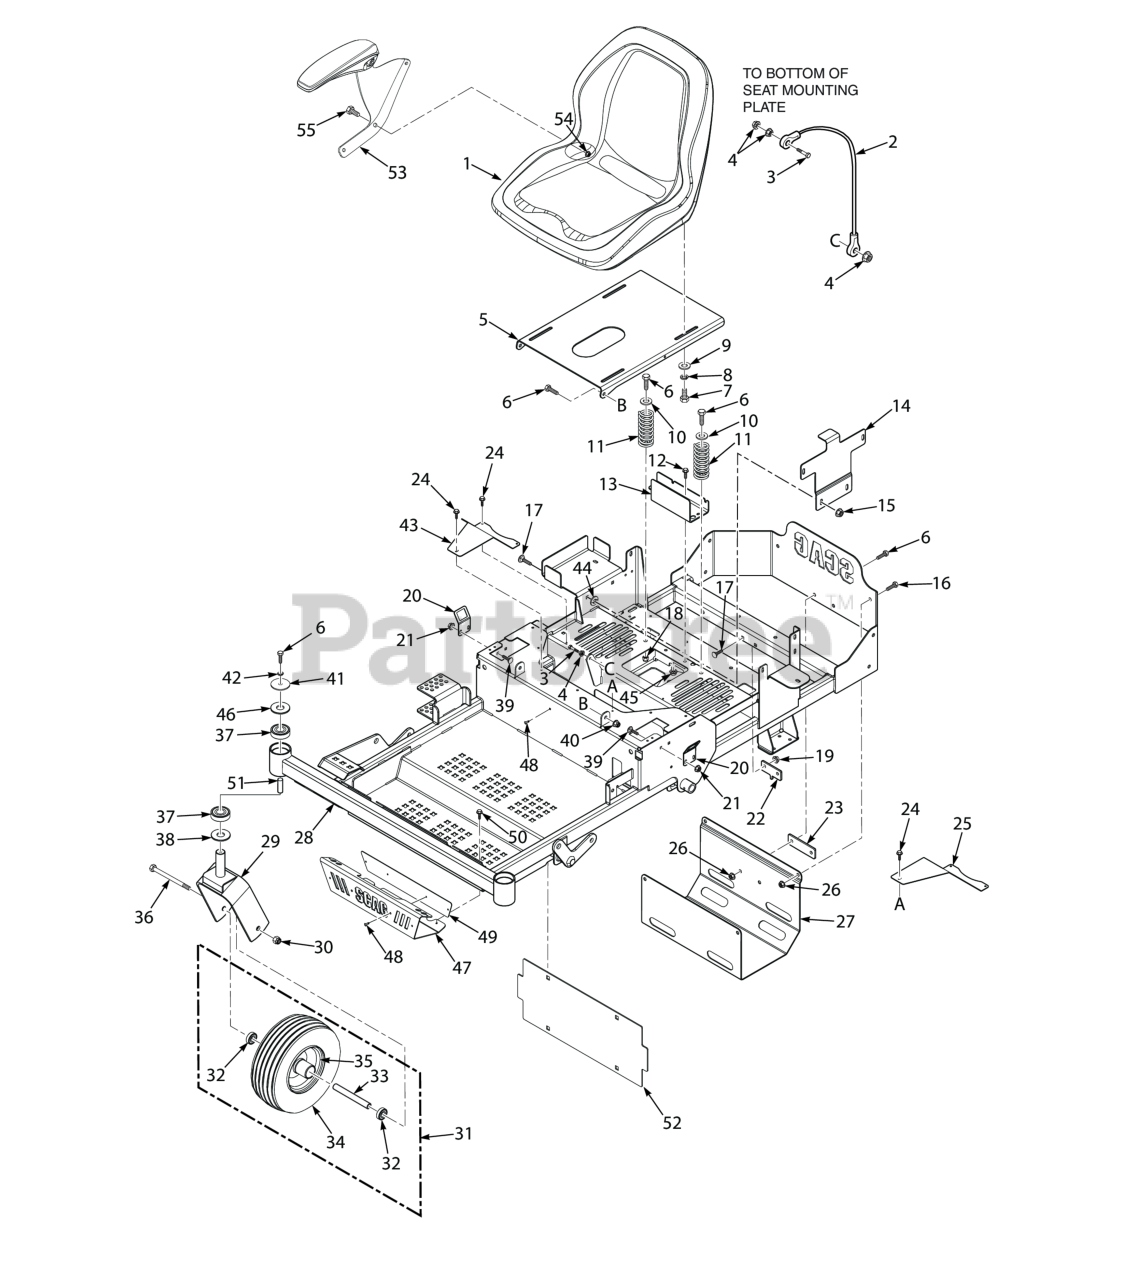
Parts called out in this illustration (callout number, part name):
1	Seat, SZL w/Armrests
2	Cable, Seat Stop
3	SERR. FLG. HEX HEAD CAPSCREW, 5/16-18 X 3/4
4	NUT, 1/4-20 SERRATED FLANGE HEX HEAD
5	Seat-Plate W/Decal
6	Bolt, Hex Head, 3/8-16 x 1 Gr. 5
7	Bolt, Heax Head 5/16-18 x 1" (48V / 52V)
8	Lockwasher, 5/16 (.317 x .586 x .078) Helical Spring
9	Flatwasher, 5/16-.375 x .875 x .083 (35BV & 37BV-EFI)
10	Flatwasher, 3/8" Special (.391 x .938 x .105)
11	Spring, Seat
12	Capscrew, 5/16-18 x .75 Serrated Flange Hex Head
13	Channel, Hose
15	Nut, Flange Head Elastic Stop 5/16-18
16	Bolt, Hex Head, 3/8-16 x 3/4"
17	Bolt, 5/16-18 x .75 RHSN Carriage
18	HEX NUT, ELASTIC STOP LOCK, 3/8-16
19	Nut, Flange Head Elastic Stop 5/16-18
20	Bracket, Switch
21	Nut, Flanged Elastic Stop 1/4-20
22	Plate, Anti-Rotation
23	Plate, Spacer
24	Screw, #10-32 x .563 Shakeproof
25	Guard, Belt - LH
26	NUT, 3/8-16 SERRATED FLANGE HEX HEAD
27	Skid Plate, SZL
28	Mainframe w/Decals - SZL
29	Caster Assembly
30	HEX LOCKNUT, ELASTIC STOP, 1/2-13
31	CASTER WHEEL ASSY, 11.00 X 6.00-5
32	Bearing
33	SPACER, WHEEL BEARING
34	TIRE, 11 X 6.00-5
35	RIM ASSY, 5 X 3 W/5.625 LG HUB
36	Bolt, Hex Head 1/2-13 x 7-1/2" (48"/52")
37	Bearing
38	Spacer, Yoke
39	Serr. Fl. Hex Head CPSCR, 1/4-20 x 3/4"
40	Nut, Flange Elastic Stop Nut, 3/8-16
41	Flatwasher, 3/8-.406 x 2.25" x .1875
42	Lockwasher, 3/8" Spring, Kawasaki FX / FS
43	GUARD, BELTS - RH
44	Nut, Push-On 5/16-18
45	Nut, Serrated Flange 5/16-18 (Right Front Engine Mounting, Briggs and Kohler Only)
46	Flatwasher, 7/16" (.500 x 1.25 x .083")
47	Bumper. Front
48	Rivot, 3/16 x .402 POP
49	Plate, Decal
50	Screw, 1/4-20 x .375"
51	Spacer, Caster Bearing
52	Plate, Backing
53	Armrest, RH (48H, 52H, 61H)
54	SPEED U-NUT,1/4-14
55	SCR,HHSCR, 1/4-14 X1 TYPA THRD FRMNG
